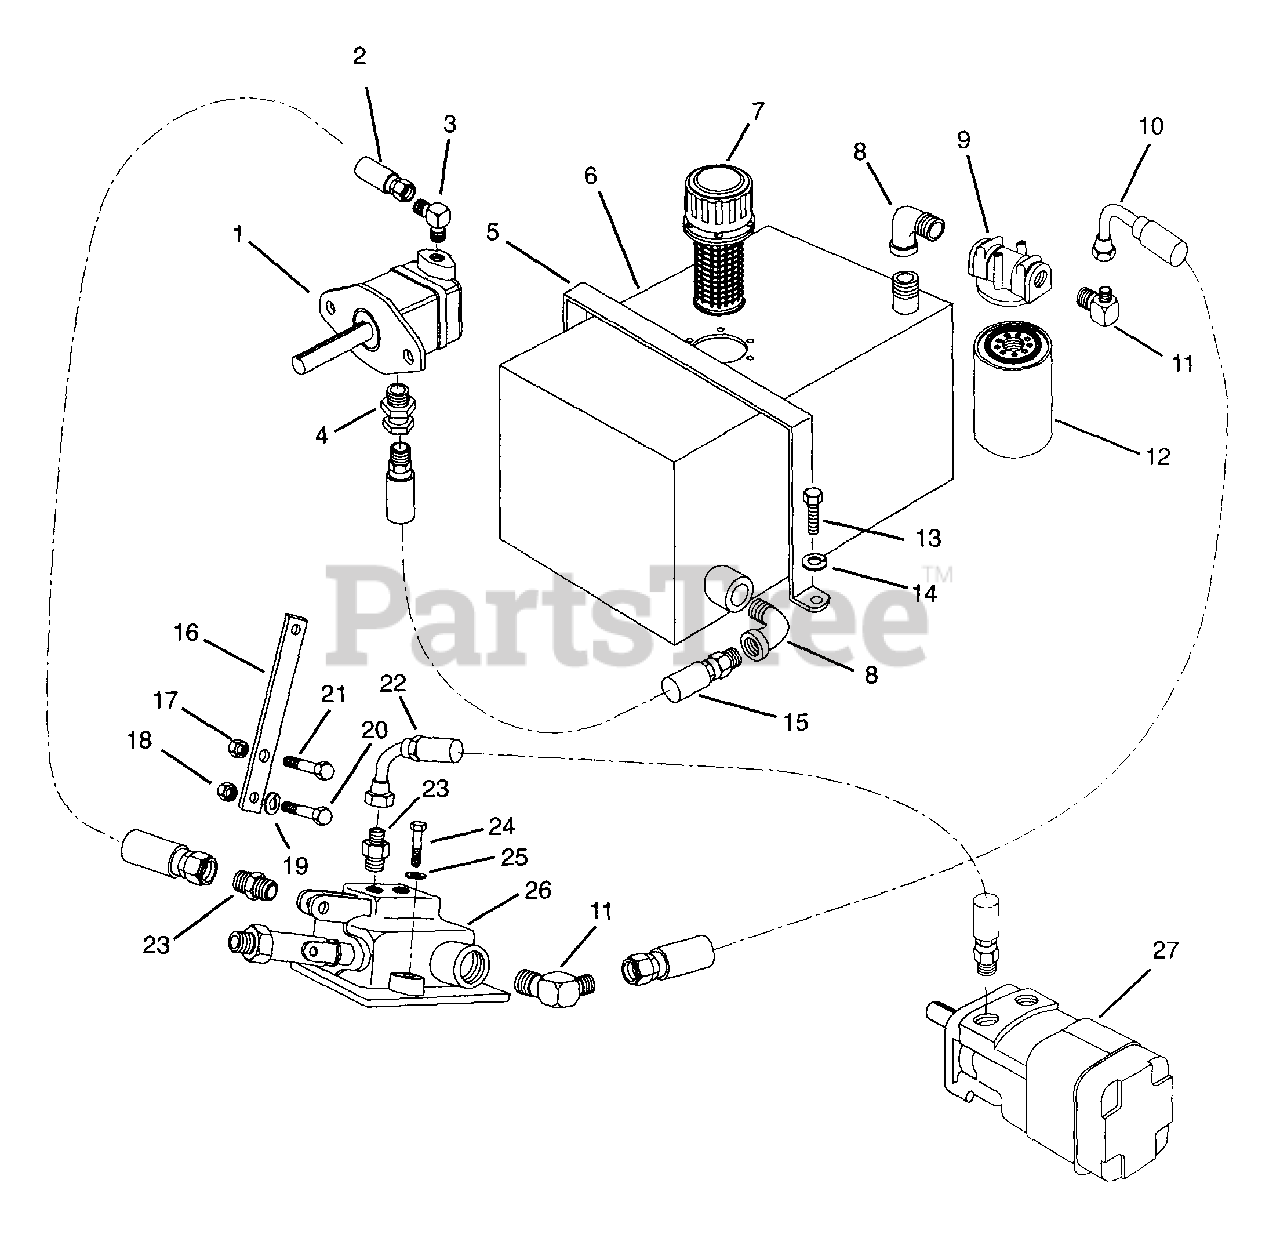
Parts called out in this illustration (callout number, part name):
1	Hydraulic Pump
2	Hydraulic Hose
3	Adapter-Pipe .75-16 "O" Ring
4	Hydraulic Swivel Fitting
5	Tank Strap
6	Hydraulic Oil Tank
7	Filler Cap Assembly
8	Street Elbow-90 Degree-Galvanized 3/4 In.
10	Hydraulic Hose
11	Hydraulic Fitting
12	Replacement Element
13	Bolt-Hex .38-16 x .75-Grade 5
14	Washer-Lock .38 x .094
15	Hydraulic Hose w/ Straight Swivel Fitting
17	Nut-Locking-Top .25-20
18	Nut-Hex Jam .25-20
19	Washer-Lock .25 x .077
20	Bolt-Hex .25-20 x 1.00-Grade 5
21	Bolt-Hex .25-20 x 1.50-Grade 5
22	Hydraulic Hose
23	Hydraulic Fitting
24	Bolt-Hex .38-16 x 1.25-Grade 8
25	Washer-Lock .38 x .094
26	Hydraulic Valve
27	Hydraulic Motor
